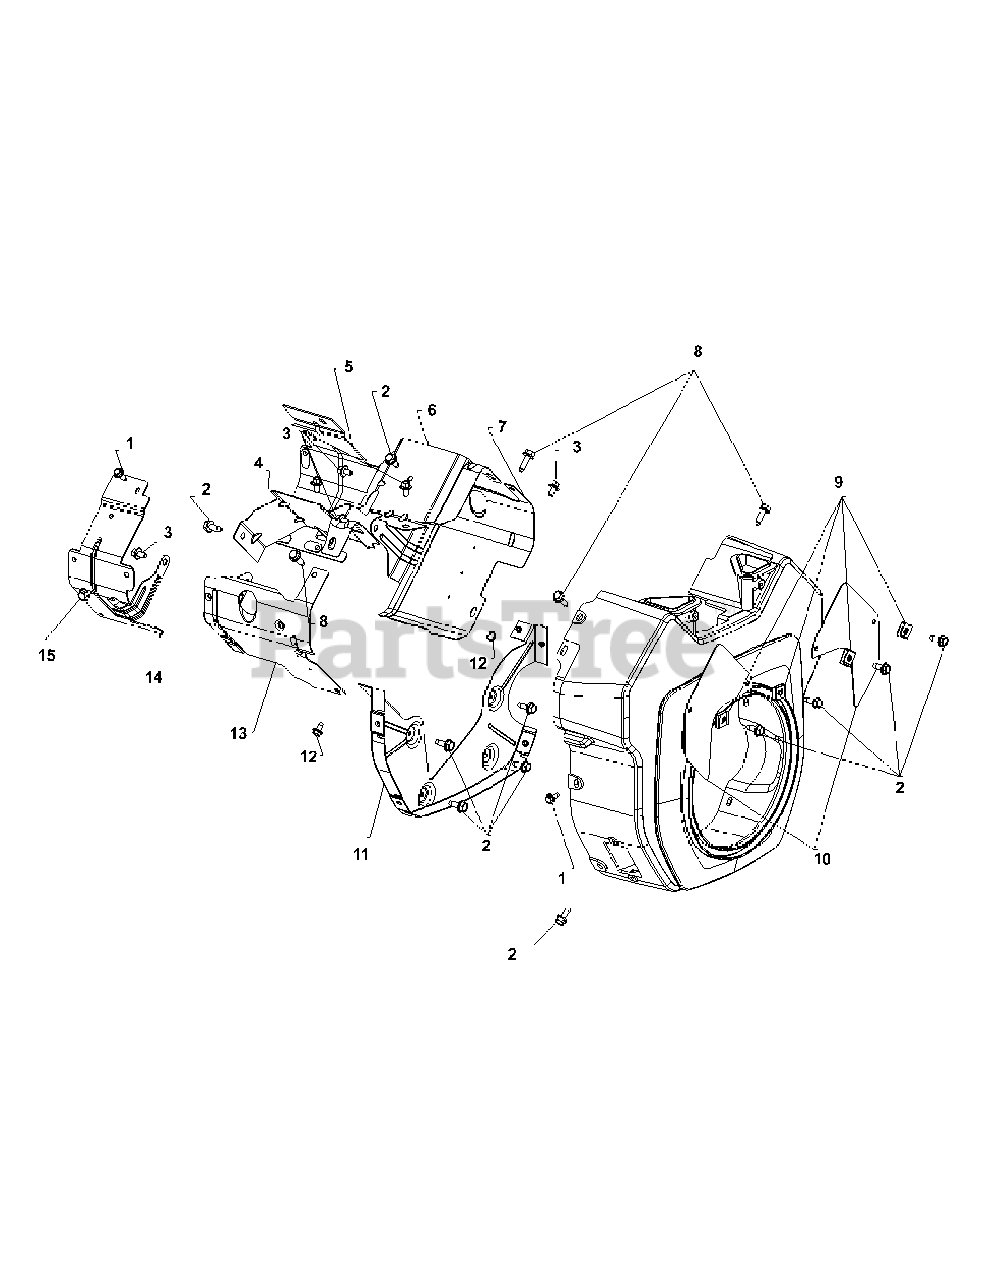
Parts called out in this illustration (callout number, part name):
1	Screw, Flg Thd Frm M5X0.8X16
2	Screw, Flg Thd Frm M6X1.0X16
3	Screw, Flg M6X1.0X10
4	Baffle, Valley #2 Cylinder
5	Baffle, Ducted Air-Starter
6	Baffle, Valley #1 Cylinder
7	Kit, Cyl Baffel #1 Side
8	Screw, Flg Thd Frm M6X1.0X20
9	Clip, Baffle Mounting
10	Kit, Access Panel
11	Kit, Backing Plate
12	Screw, Flg Thd Frm M5X.8X10
13	Kit, Cyl Baffel #2 Side
14	Baffle, Ducted Air-Oil Filter
15	Screw, Flng Thd Frm M6X1.0X10
